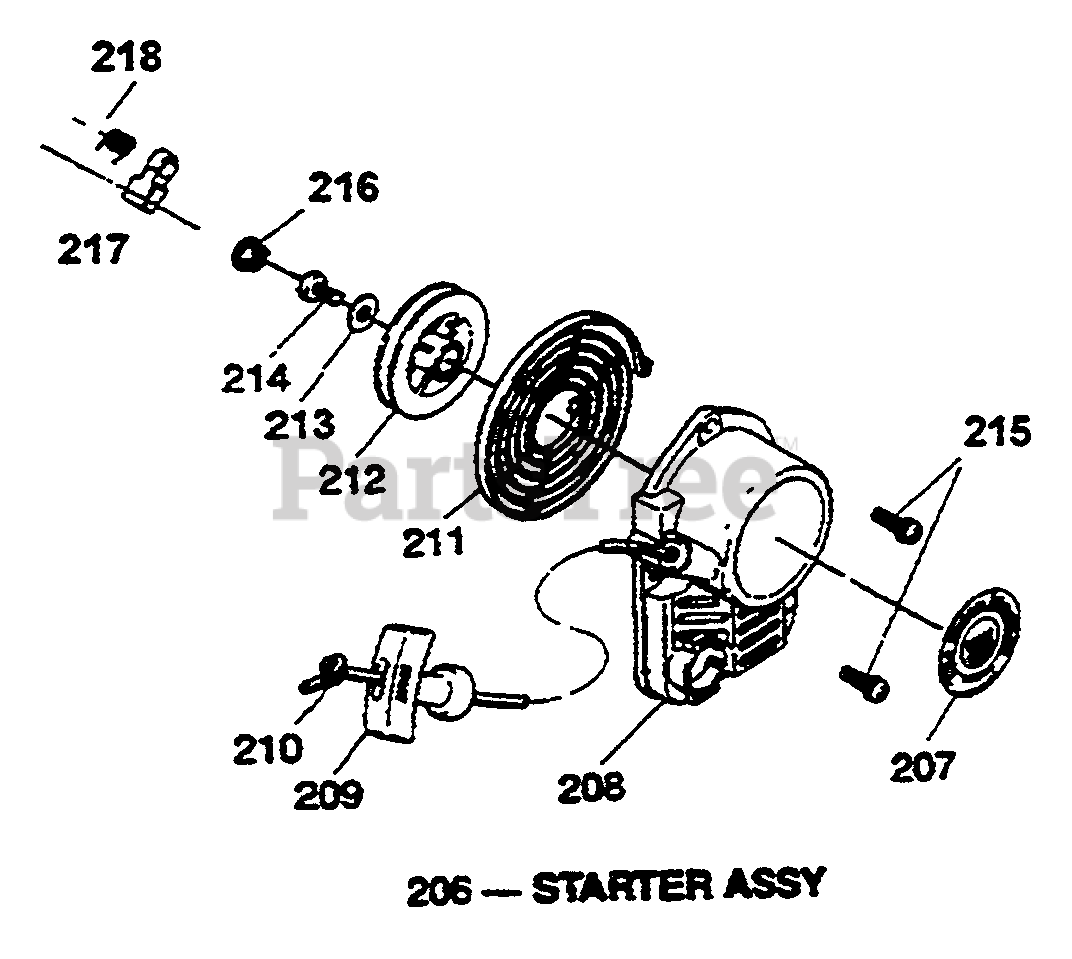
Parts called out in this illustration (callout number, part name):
206	STARTER ASSY (W/HOLE)
207	LABEL NAME
208	CASE, STARTER (W/HOLE)
209	KNOB, STARTER
210	ROPE, STARTER
211	SPR1NG, SPIRAL
215	BOLT AND WASHER
